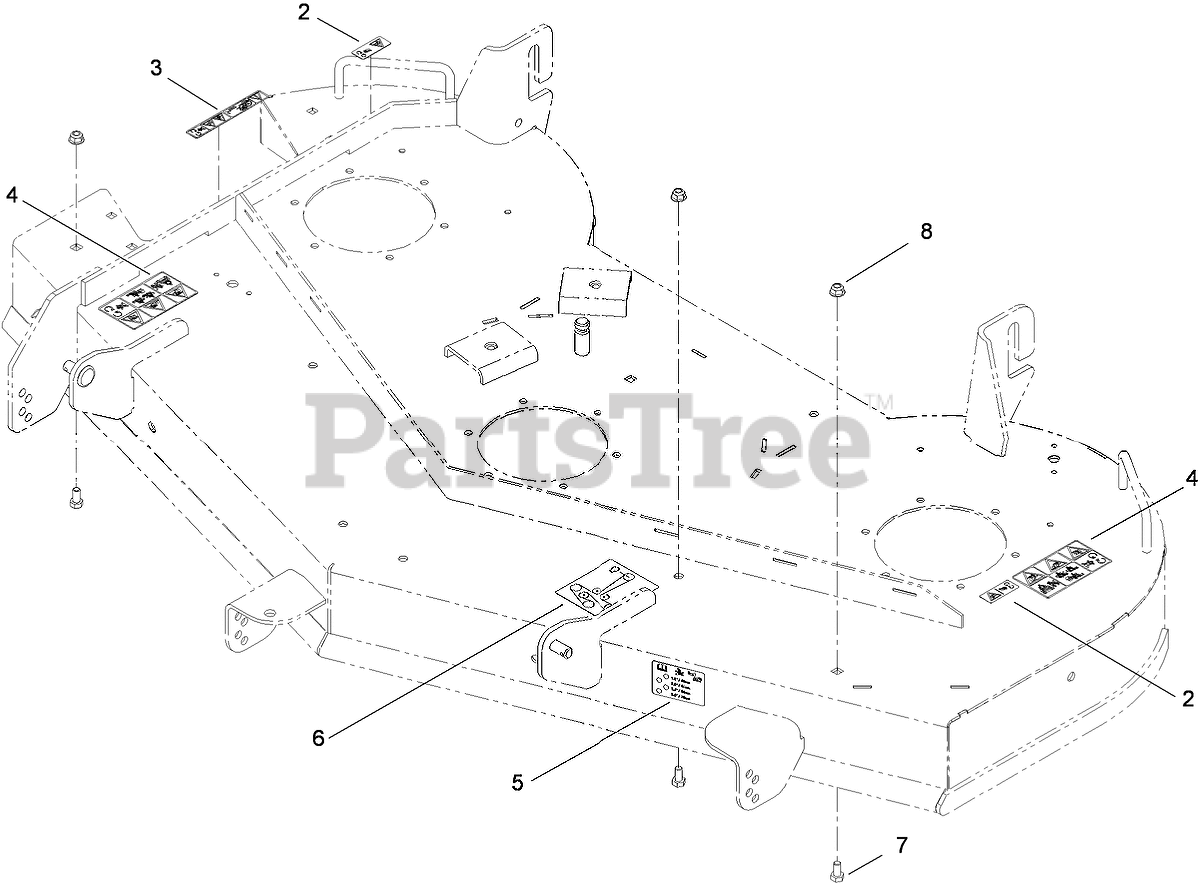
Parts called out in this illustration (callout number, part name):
2	DECAL-DANGER
3	DECAL-DANGER
4	DECAL-DANGER
5	DECAL-SCALP, ANTI
6	DECAL-ROUTING, BELT
7	SCREW-HH
8	NUT-HF, NI
